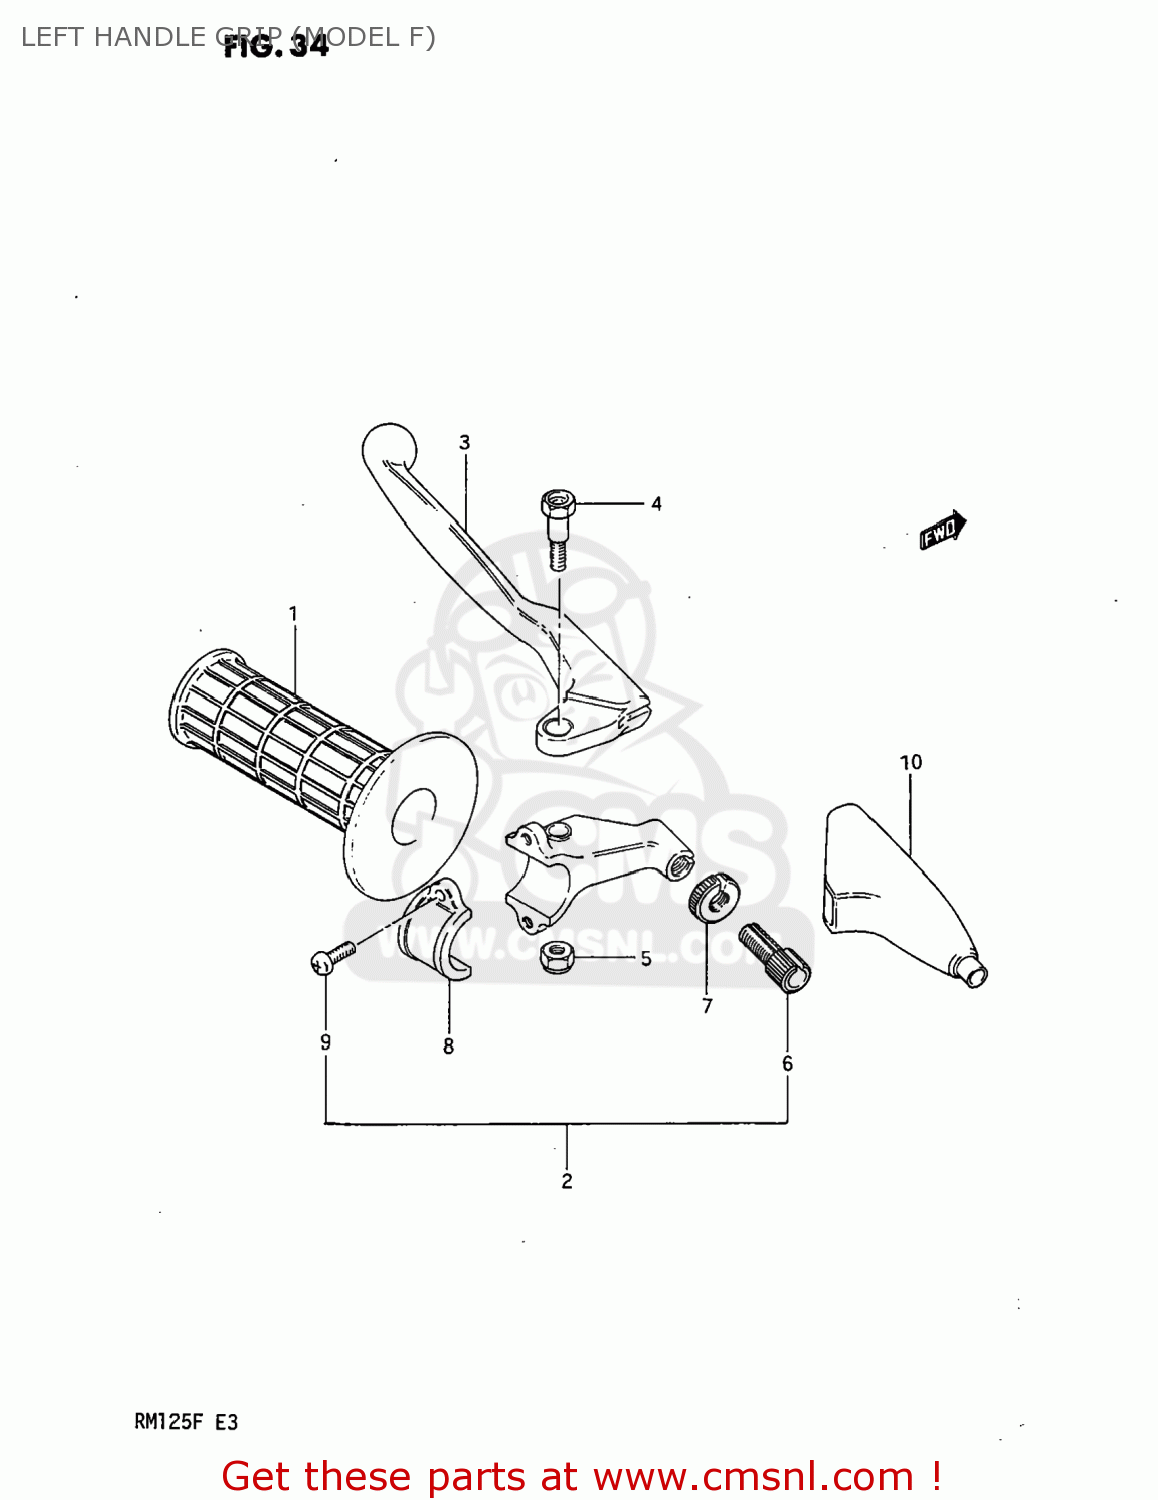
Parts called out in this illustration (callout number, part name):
1	GRIP,LEFT
2	LEVER ASSEMBLY
3	LEVER,CLUTCH
4	BOLT,LEVER
5	NUT
6	ADJUSTER,CABLE
7	NUT,CABLE ADJUSTER LOCK
8	HOLDER,LEVER
9	SCREW (5X14)
10	COVER,CLUTCH LEVER
